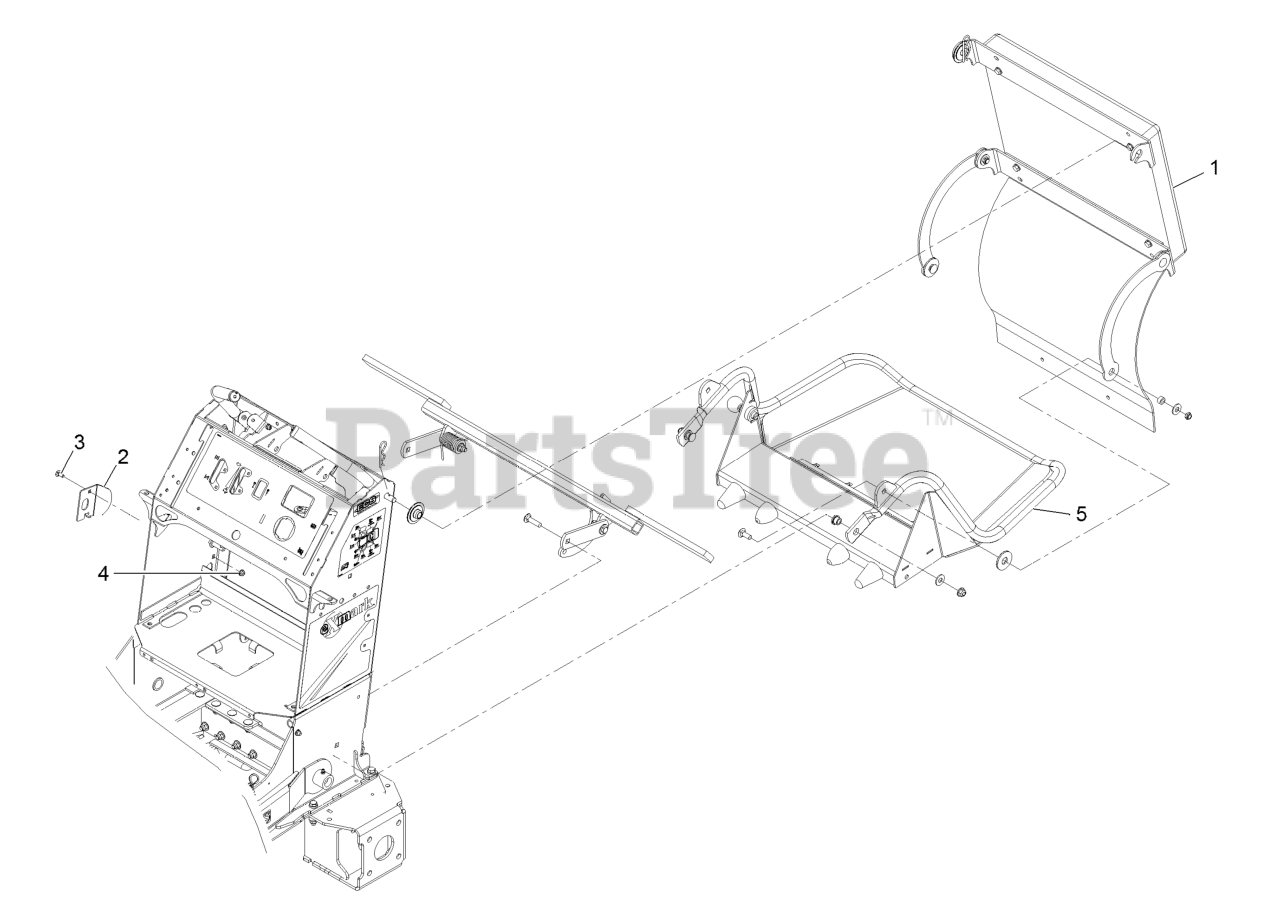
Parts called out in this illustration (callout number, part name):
2	PLATE-STRIKER
3	SCREW-CARR
5	ASM,PLATFORM
